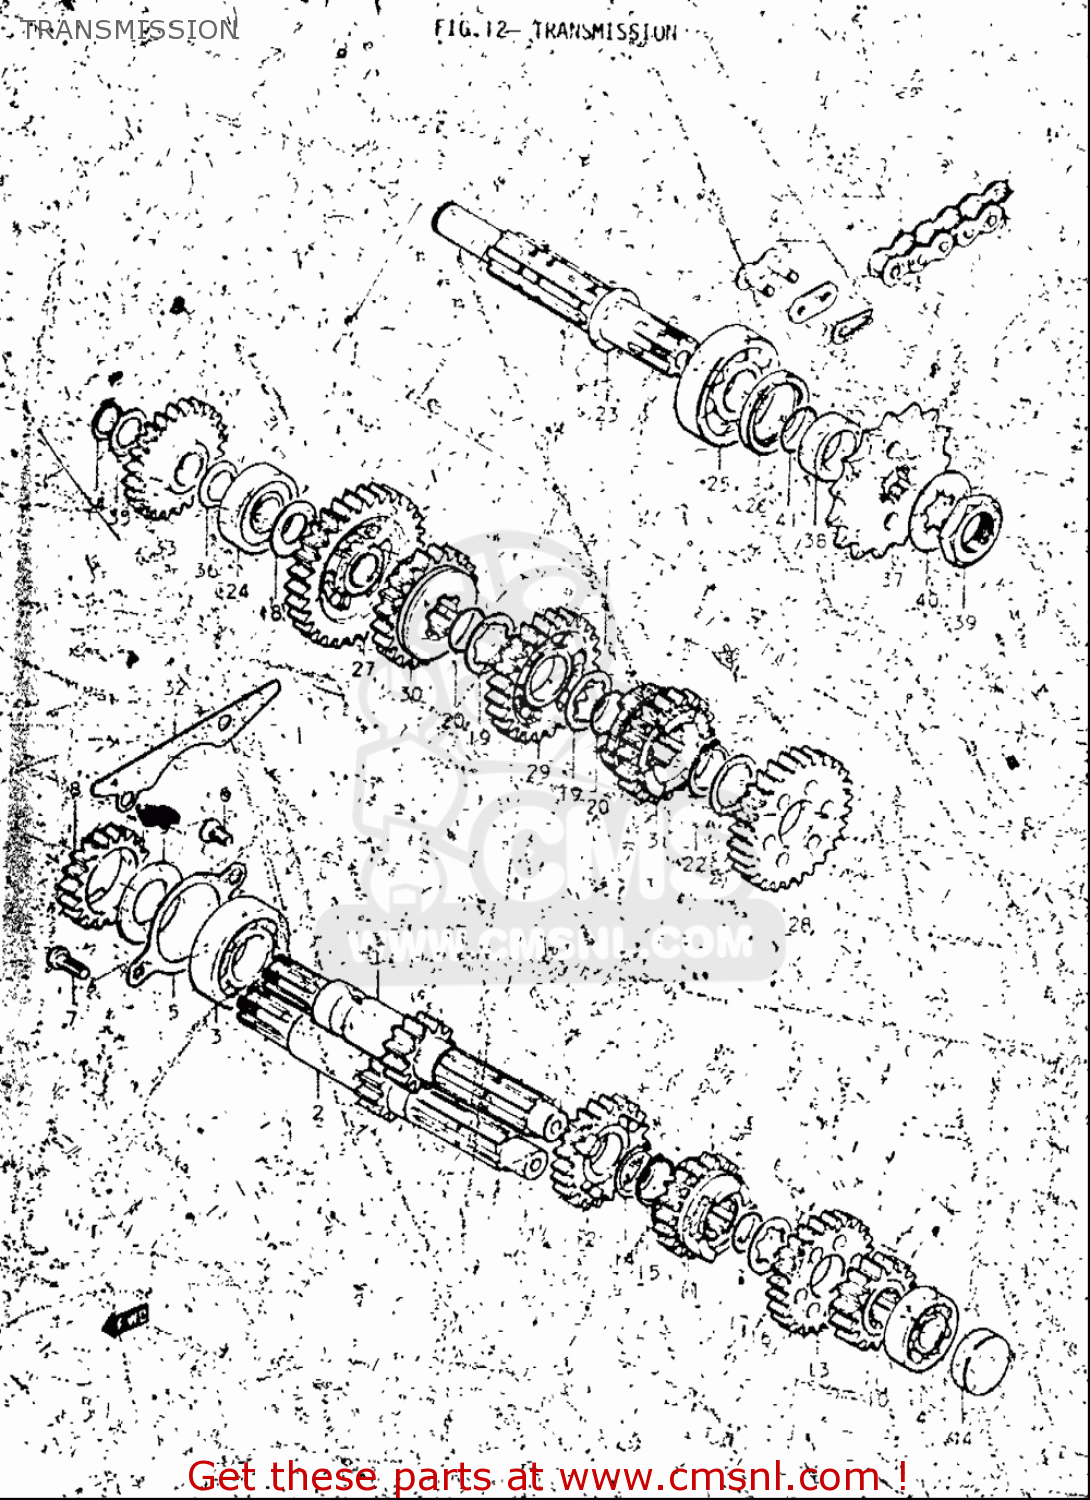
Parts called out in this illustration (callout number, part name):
3	BEARING
4	BEARING(17X40X12)
5	PLATE,COUNTERSHAFT BEARING
6	SCREW
7	SCREW
9	WASHER(25X41X3)
13	GEAR,FIFTH DRIVE
14	SHIM(22X28X1)
15	CIRCLIP
16	WASHER,LOCK
17	CIRCLIP
18	SHIM(17X30X1)
19	WASHER
20	RING,SNAP
21	WASHER
22	RING,SNAP
24	BEARING
25	BEARING(22X56X16)
26	SEAL,OIL(32X42X6)
27	GEAR,FIRST DRIVEN
31	GEAR,5TH DRIVEN
33	GEAR,KICK STARTER IDLE
34	CIRCLIP
35	WASHER
36	WASHER
37	SPROCKET,ENGINE
38	SPACER(22X32X11.5)
39	NUT
40	WASHER,LOCK
41	O RING(D:1.7,ID:22)
42	CHAIN,DRIVE #525TR-10
43	JOINT ASSEMBLY,CHAIN
44	PLUG
